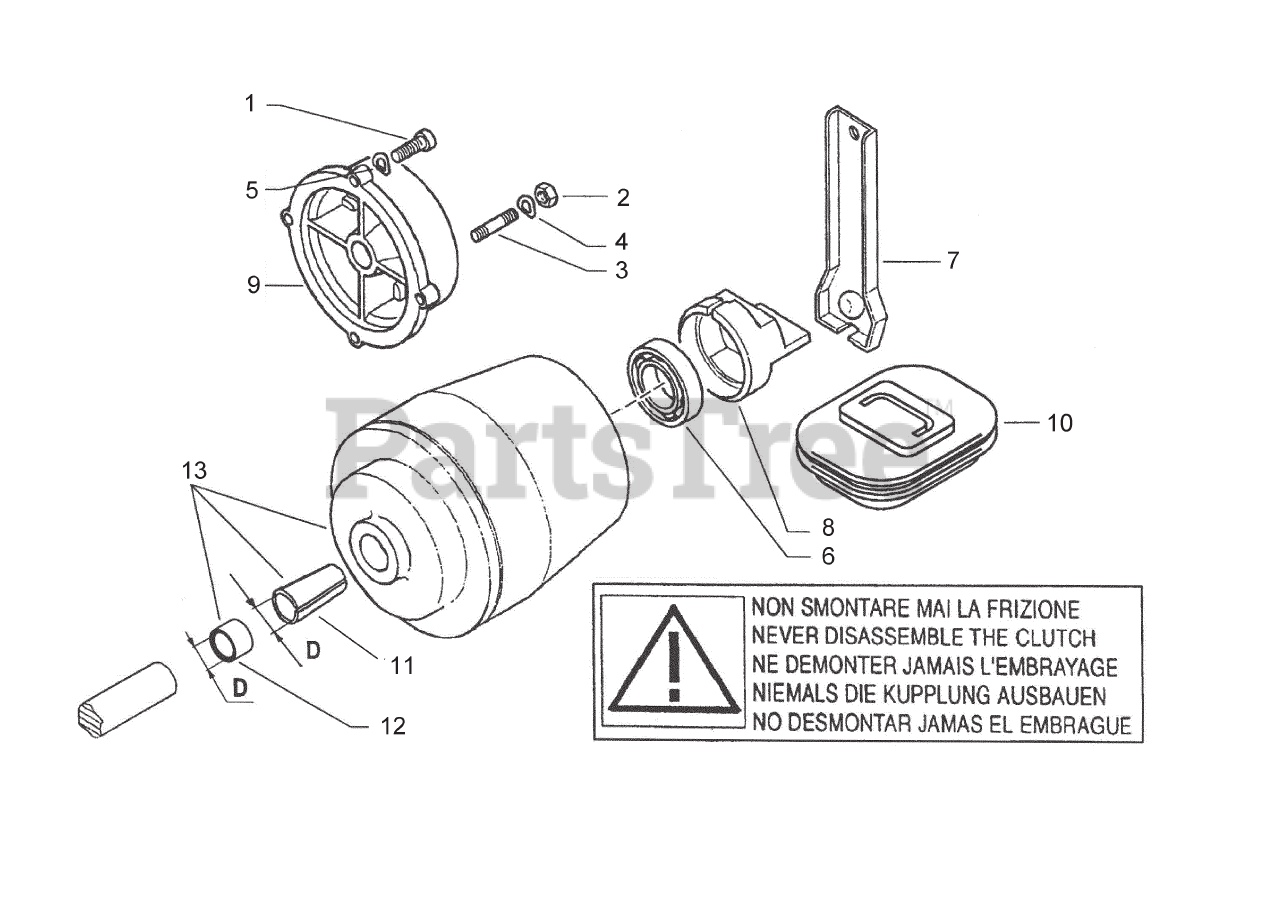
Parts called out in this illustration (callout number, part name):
1	SCREW, 3/8X1"
2	NUT, M8
3	STUD, M8X40X14X14
4	WASHER, WAVE
5	WASHER, WAVE
6	BEARING, M17X40X12
7	LEVER, RECOIL START
8	PUSHER CONE
9	FLANGE
11	SPACER
12	SPACER
13	CLUTCH (INCLUDES 6 & 8), HONDA GX240 - GX270
